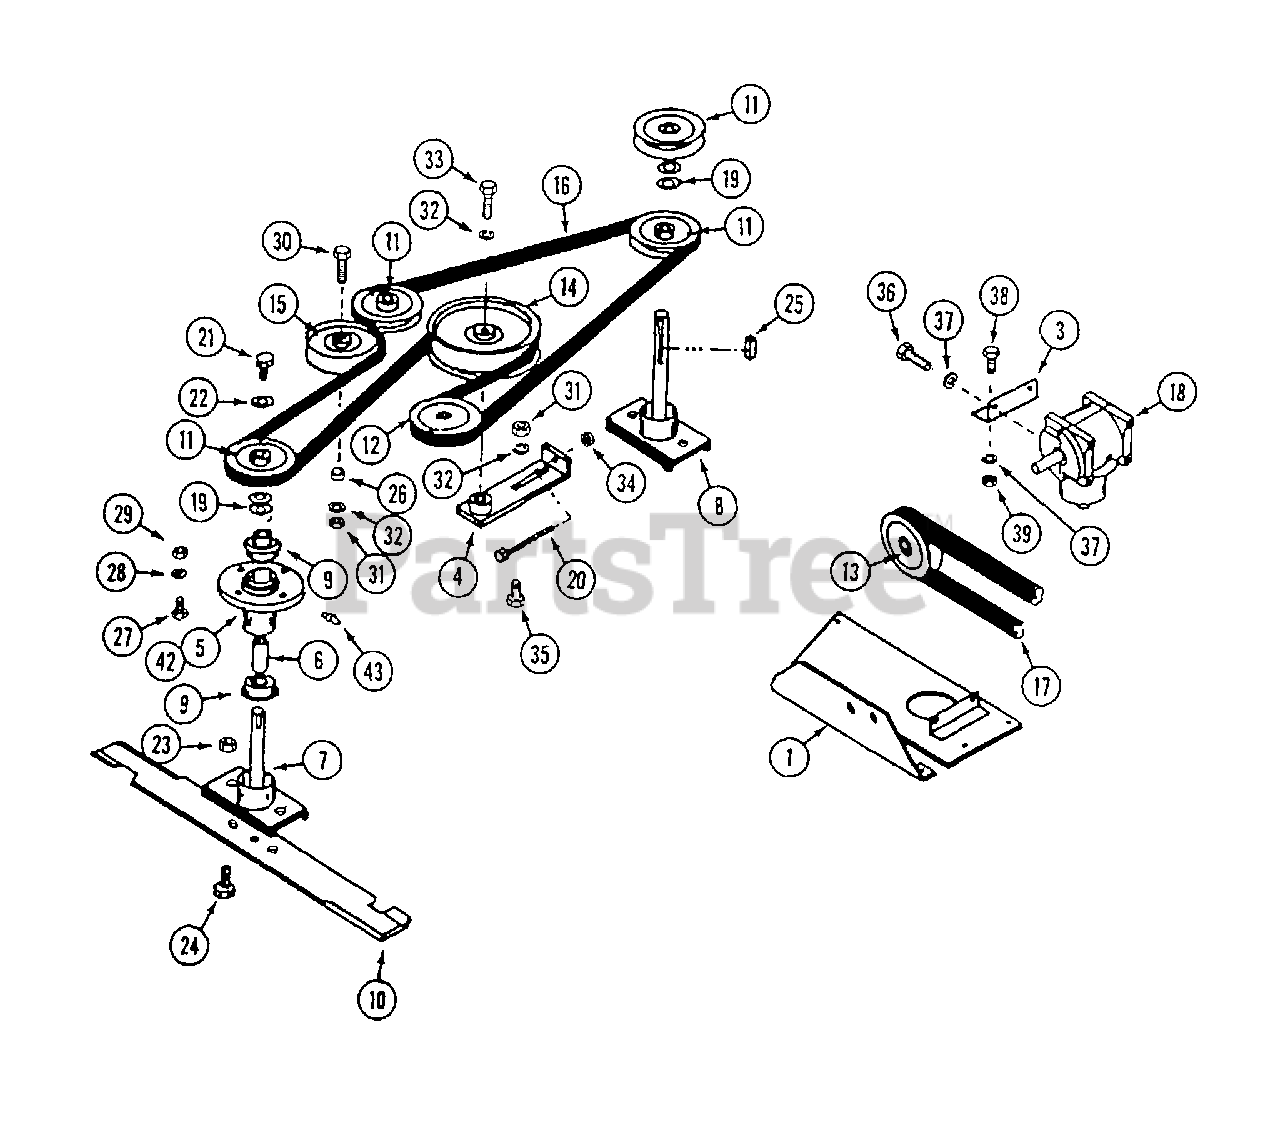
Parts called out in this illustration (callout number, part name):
1	MOUNT - gear box
3	ANGLE - gear box mount
4	TIGHTENER - belt
5	HOUSING - spindle
6	SPACER - spindle
7	SHAFT - spindle
8	SHAFT - spindle, long
9	BEARING - spindle
10	BLADE - mower
11	PULLEY - spindle
12	PULLEY - gear box output
13	PULLEY - gear box input
14	PULLEY - idler, large 6"
15	PULLEY - idler, small
18	GEAR BOX - angle drive
19	SPACER - washer
20	BOLT - 1/4" - 20 x 4"
21	BOLT - 3/8" - 24 x 1-1/4"
22	WASHER - 3/8" hardend
23	NUT - 3/8" - 16 lock
24	BOLT - 3/8" - 16 x 1"
25	KEY - 3/16" x 1"
26	SPACER - idler pulley
27	BOLT - 7/16" - 14 x 1-1/4"
28	LOCKWASHER - 7/16"
29	NUT - 7/16" - 14
30	BOLT - 3/8" - 16 x 2-1/2"
31	NUT - 3/8" lock
32	LOCKWASHER - 3/8"
33	BOLT - 3/8" - 16 x 1-1/4"
34	NUT - 1/4" - 20 lock
35	BOLT - 3/8" - 16 x 1" carriage
36	BOLT - 5/16" - 18 x 1"
37	LOCKWASHER - 5/16"
38	BOLT - 5/16" - 18 x 3/4"
39	NUT - 5/16" - 18
42	HOUSING ASSEMBLY - spindle
43	FITTING - grease 1/4" - 28
